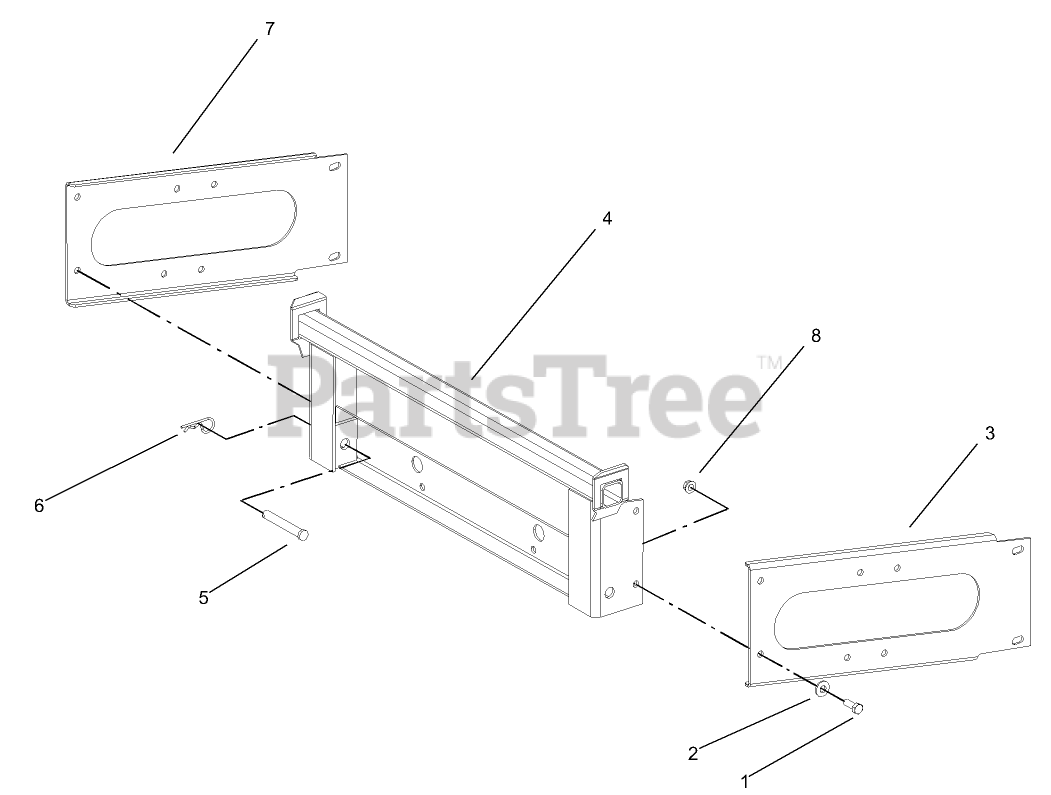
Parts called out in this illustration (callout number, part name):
1	SCREW-HH
2	WASHER-BELLEVILLE
3	BRACKET-FRAME, RH
4	MOUNT-BAGGER
5	PIN-CLEVIS
6	PIN-COTTER
7	Bracket-Frame, LH
8	NUT-HHF, WHIZ
